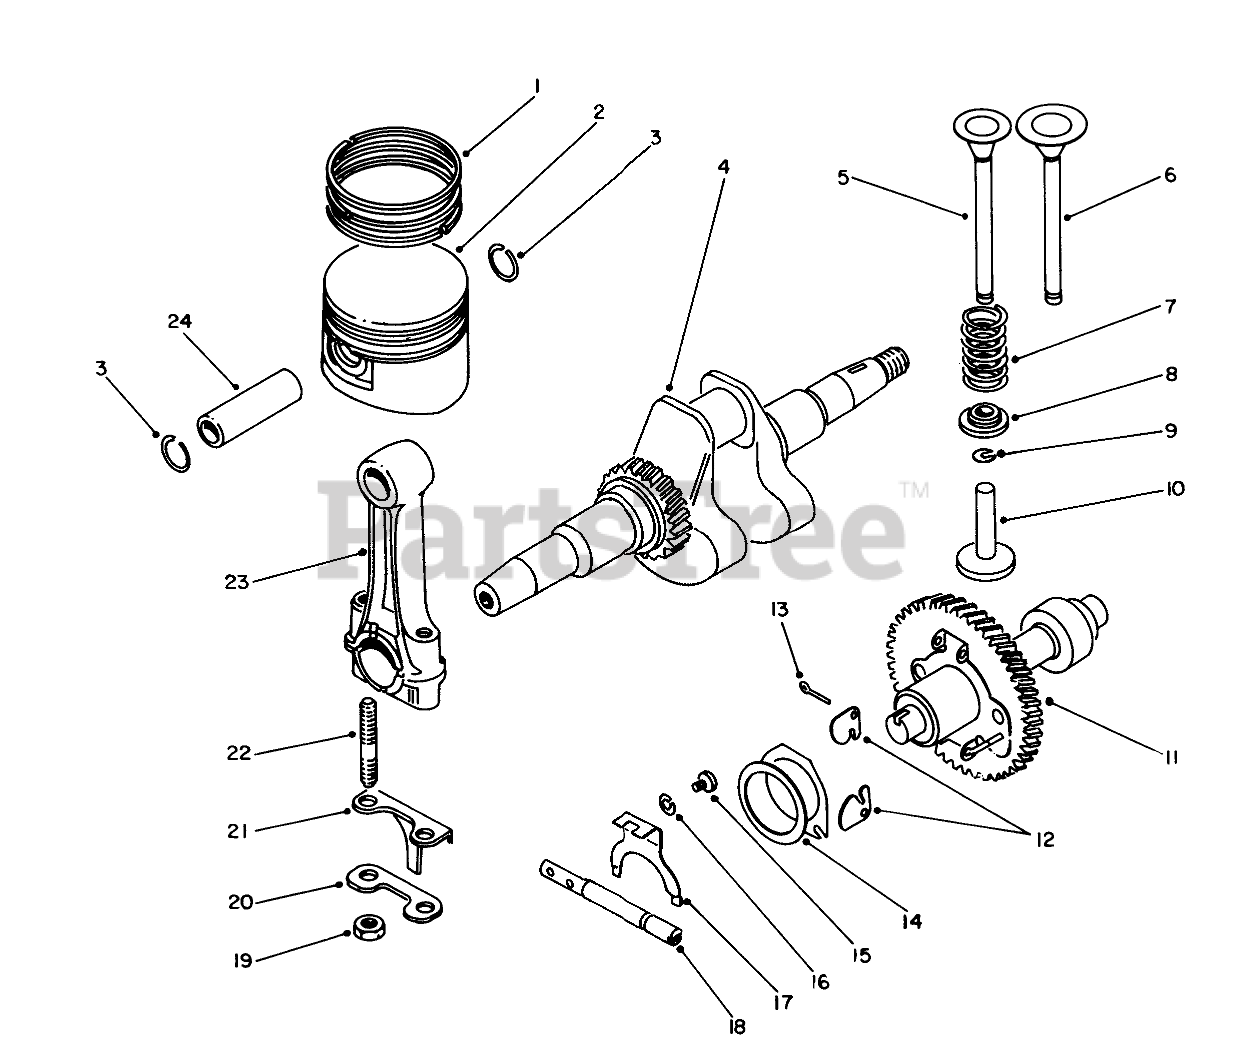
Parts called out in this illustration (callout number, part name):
1	Ring Set-Piston Std.
2	Piston Std.
3	CIRCLIP
4	Crankshaft
5	Valve-Exhaust
6	Valve-Intake
7	Spring-Valve
8	Retainer
9	Cotter
10	Tappet (L:36.46)
11	Cam Shaft
13	Cotter Pin
14	Spacer
15	SCREW
16	Washer
17	Plate-Shift
18	Shaft-Throttle Return
20	LOCK PLATE
21	PLATE
22	Stud Bolt
23	Rod-Connecting (Std.) (Incl. Ref. #19-22)
24	PISTON PIN
